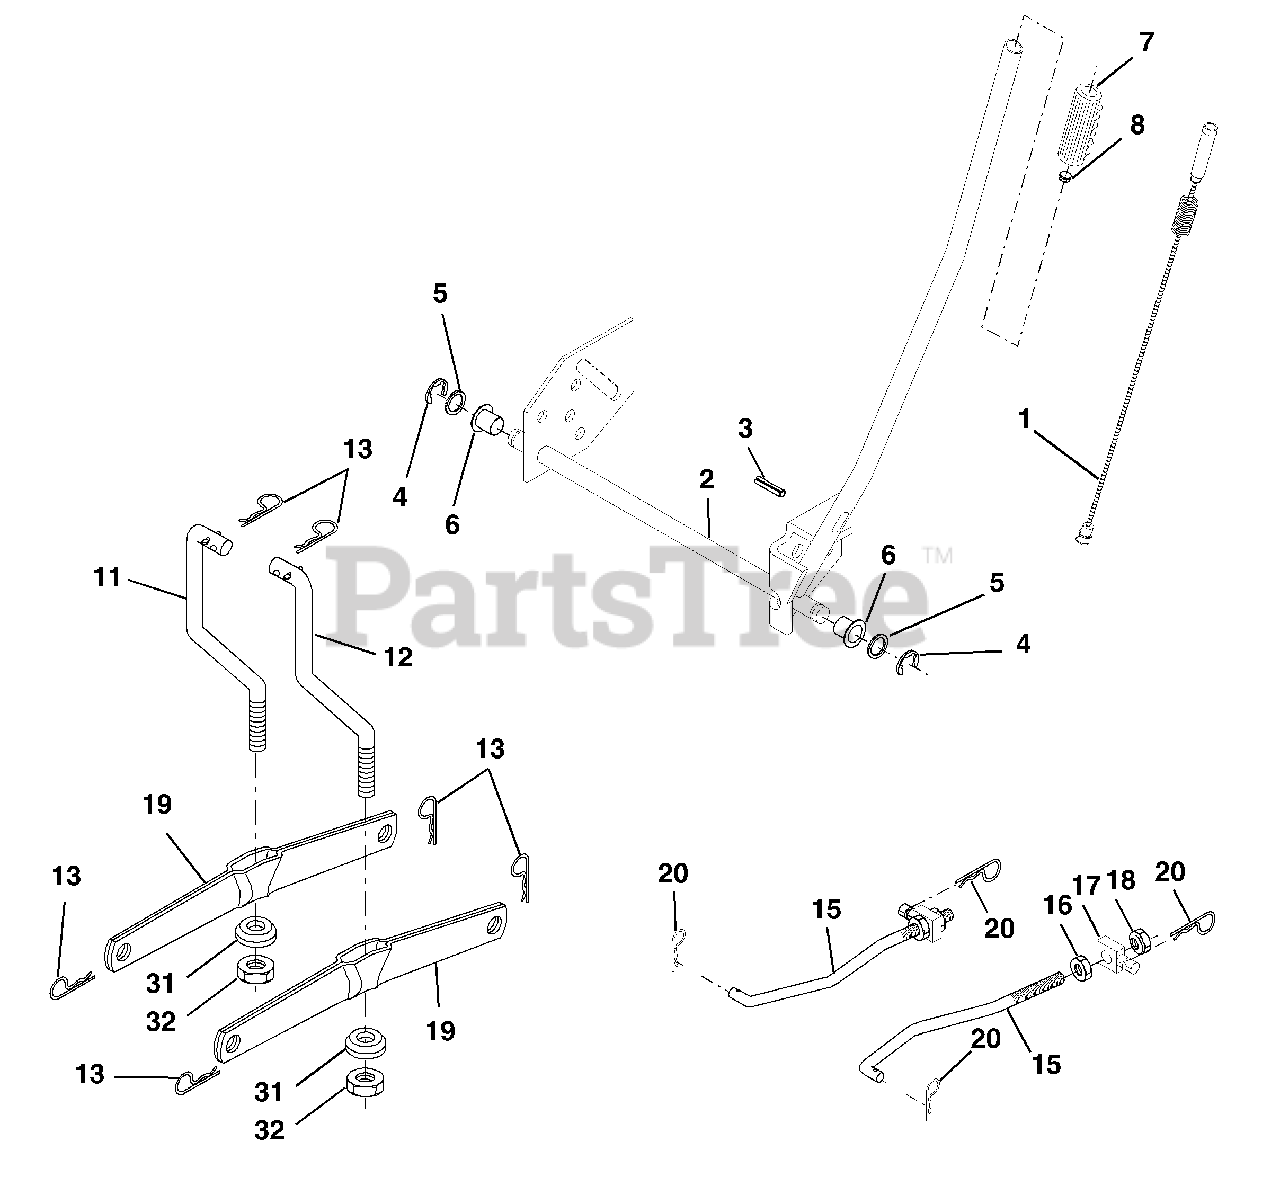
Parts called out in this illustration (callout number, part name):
1	Wire Asm Inner W/plunger
2	Shaft Asm Lift RH w/Inf
3	Pin Groove 1 500 Zinc
4	E Ring #5133-62
5	Washer 21/32 X 1 X 21 Ga
6	Bearing Nylon Blk 629 Id
7	Grip Handle Fluted Blk
8	Button Plunger Black
11	Link Lift LH Fixed Length
12	Link Lift RH Fixed Length
13	Retainer Spring
15	Link Front
16	Nut Jam Hex 1/2-13 Unc
17	Trunnion Blk Zinc
18	Nut Lock w/Wsh 1/2-13unc
19	Arm Suspension Rear
20	Retainer Spring
31	Bearing Pvt Lift
32	Nut Crownlock 3/8 - 24
